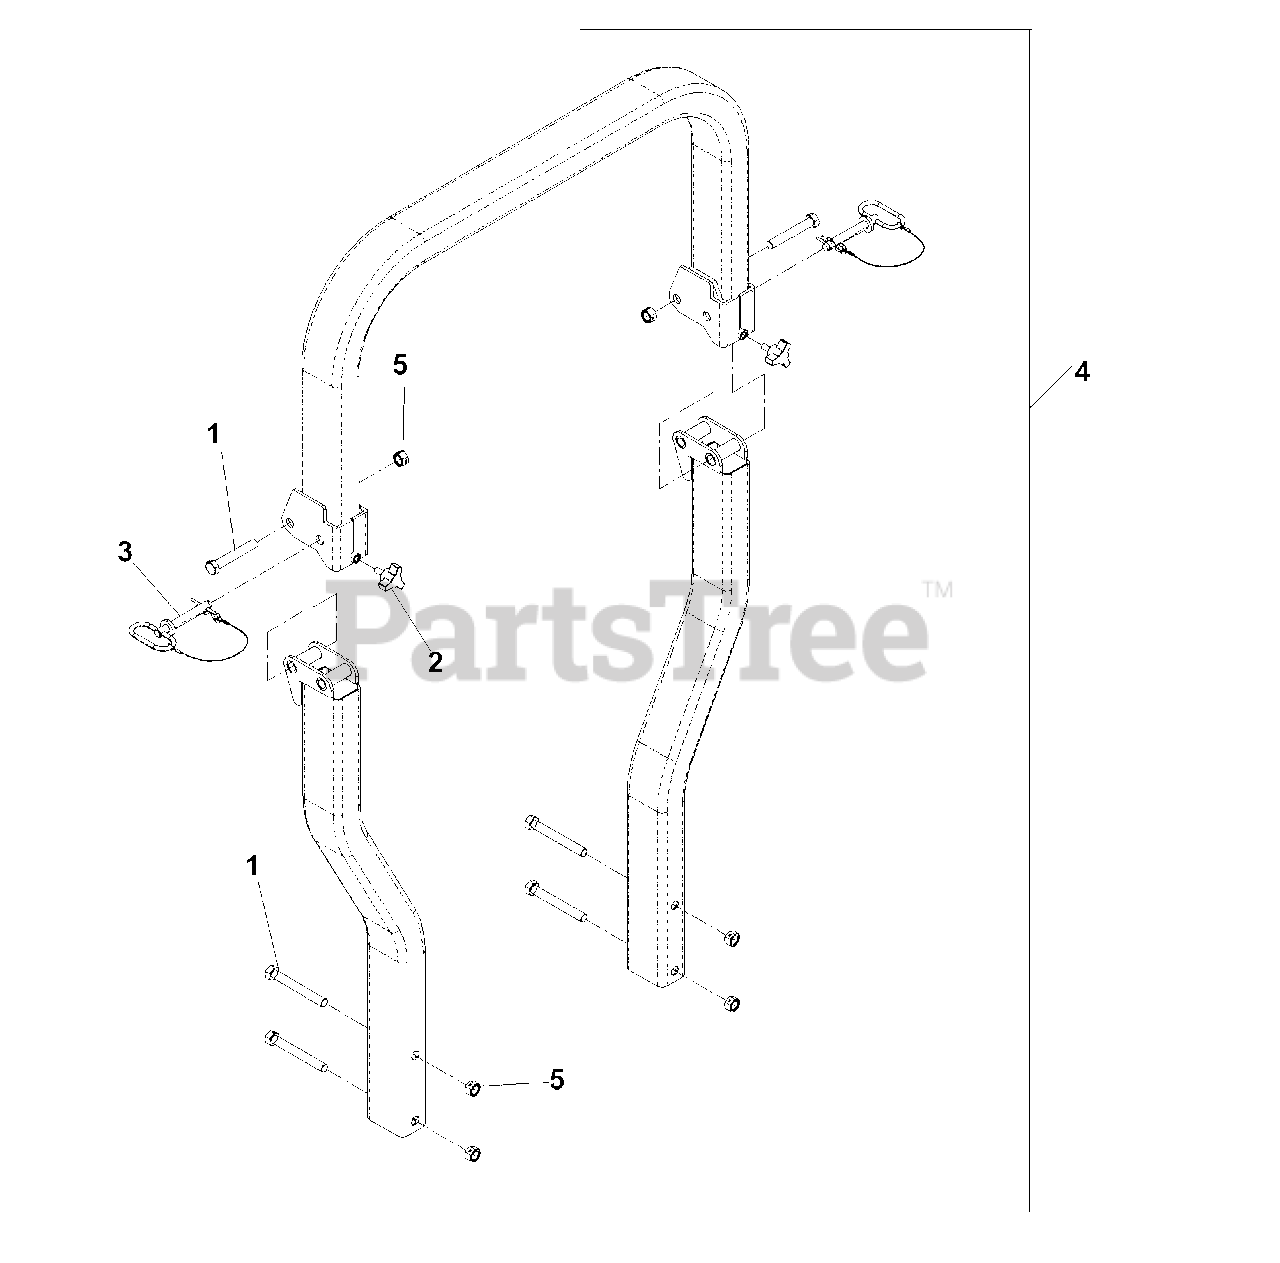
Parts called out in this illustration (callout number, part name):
1	HCS 1/2C X 3 1/4
2	KNOB W/STUD
3	PIN, 1/2" W/LANYARD
4	ROLL OVER PROTECTION SYSTEM
5	NUT 1/2-13 HEX CNTRLK GR 5 ZD
